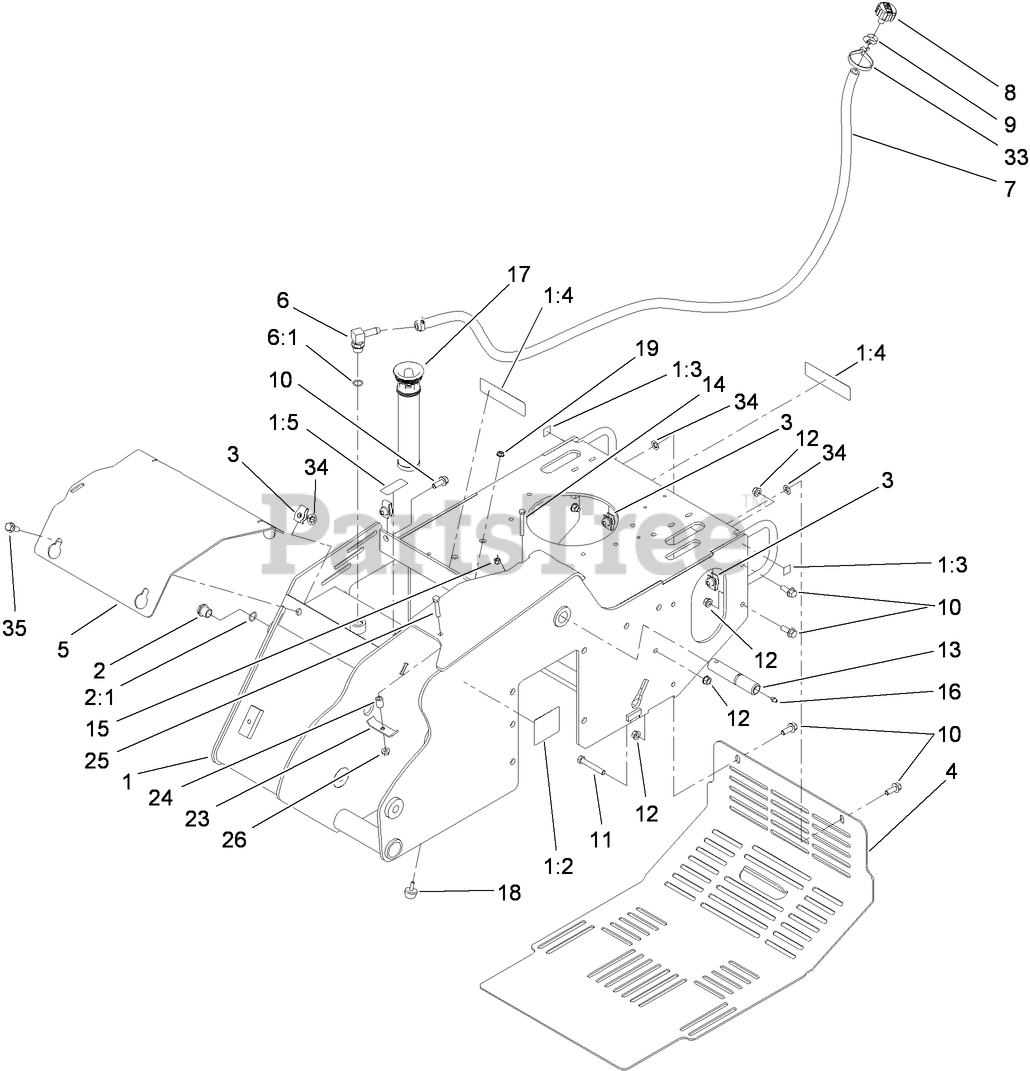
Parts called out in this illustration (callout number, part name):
1	MAIN FRAME ASM
1:2	DECAL-WARNING
1:3	DECAL-POINT, LIFT
1:4	DECAL-DANGER
1:5	DECAL-OIL, HYD
2	SIGHT GLASS ASM
2:1	O-RING
3	NUT-CLIP, U
4	COVER-REAR
5	PLATE-COVER, FRONT
6	FITTING-ELB 90
6:1	O-RING
7	HOSE-BREATHER
8	BREATHER
9	CLAMP-HOSE
10	SCREW-HHF
11	SCREW-HH
12	NUT-FLANGE
13	PIN-PIVOT
14	SCREW-HH
15	NUT-LOCK, NI
16	FITTING-GREASE
17	IN-TANK FILTER ASM
18	BUMPER
19	NUT-HF
23	BRACKET-CLAMP
24	SPACER
25	SCREW-HH
26	NUT-HF
33	TIE-CABLE
34	NUT-PUSH
35	SCREW-HHF
